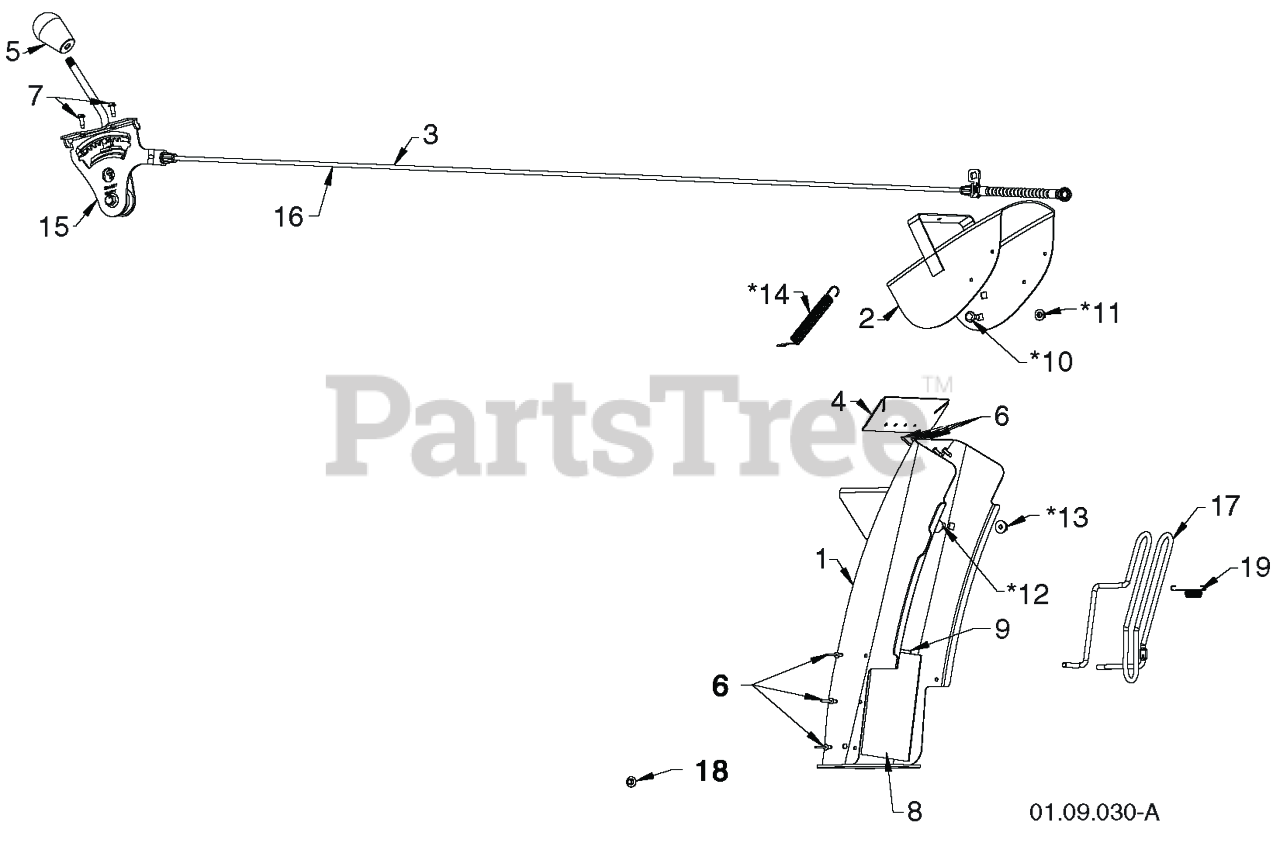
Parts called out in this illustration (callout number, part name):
1	CHUTE.WELDMENT.SNOW.ORANGE
2	DEFLECTOR.WELDMENT.PNT.ORANGE
3	RP.CONTROL.ASM.DEFLECTOR.SNOW
4	SEAL.DEFLECTOR
5	KNOB.OVERMOLD.DS.HUSQVARNA/BLK
6	RIVET BLIND
7	SCREW #10-24 X 5/8
8	SHIELD.SNOW.CHUTE
9	STRAP.SHEILD.RETAINER
15	RP CNTRL.HEAD.ASSEM.DEFLECTOR
16	RB SERVICE.CHUTE.DEF.CBL.BLK
17	ROD.GUARD.CHUTE (2 2)
18	NUT
19	SPRING.CHUTE.GUARD
